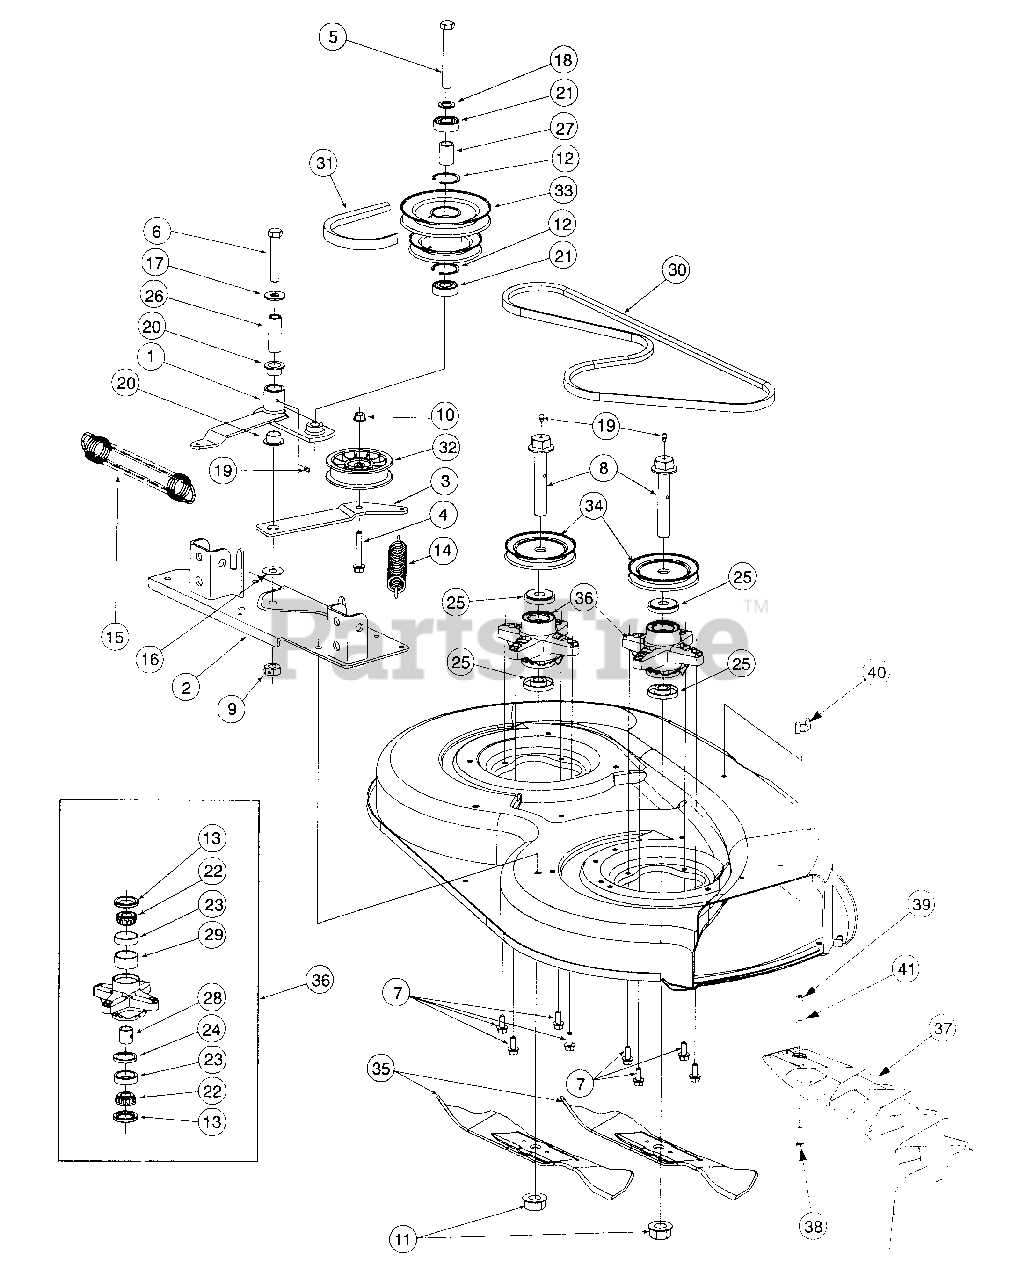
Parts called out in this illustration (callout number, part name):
1	Pivot Arm, Double Pulley
2	Plate Assembly, Mounting
3	Arm, Idler
4	Screw, Hex Cap, 3/8-16 x 1.5 GR5
5	Screw, Hex Cap, 5/8-18 x 3.0 GR5
6	Screw, Hex Cap, 1/2-20 x 3.0 GR8
7	Screw, Hx Wsh Hd Tapp, 5/16-18 x .75
8	Bolt, Spindle, 3/4-16 x 4.25
9	Nut, Hex Center Lock, 1/2-20
10	Nut, Hex Flange Lock, 3/8-16
11	Nut, Hex Flange, 3/4-16
12	Snap Ring, Internal
13	Seal, Oil, 1.25 x 1.874 x .25
14	Spring, Extension, .88 x 6.12
15	Spring, Extension, 1.25 x 8.15
16	Washer, Flat, .531 x 1.25 x .036
17	Washer, Flat, .531 x 1.25 x .100
18	Washer, Flat, .63 x 1.0 x .063 Hdn
19	Fitting, 3/16 Drive Lube
20	Bearing, Flange, 3/4 ID x .53 Lg
21	Bearing, Ball, .62 ID x 1.57 OD
22	Cone, Bearing
23	Cup, Bearing
24	Spacer, Bearing
25	Spacer, Deck Spindle
26	Spacer, Idlr Brkt .50 ID x .75 OD x 2.25
27	Spacer, Pulley, .635 ID x .88 OD x 1.25
28	Spacer, Bearing, .780 x .963 x .7777
29	Spacer, Bearing, 1.615 x 1.86 x .8427
30	Belt, Spindle, A-Section x 59 Lg
31	Belt, PTO, B-Section x 112.4 Lg
32	Pulley, Flat Idler, 3.5 OD
33	Pulley, Double
34	V-Pulley, 4.0 Dia
35	Blade, 3 In One, 19.38 Lg
36	Spindle Assy,
37	Plug, Mulch
38	Screw, Hex Cap, 1/4-20 x 1.0 GR5
39	Nut, Hex, 1/4-20
40	Nut, Wing, 1/4-20
41	Washer, Flat, .28 x .74 x .063
